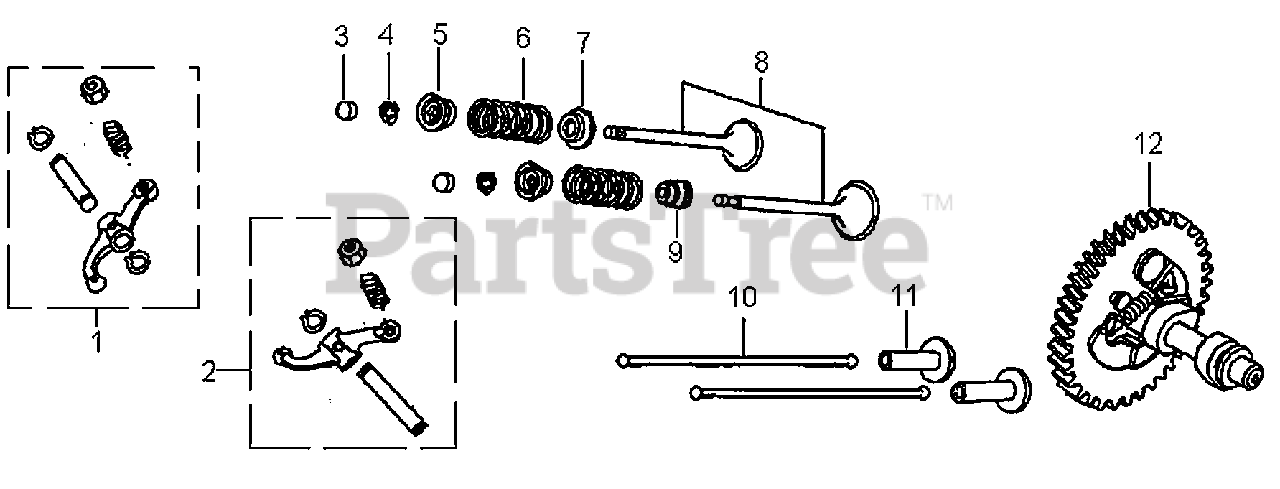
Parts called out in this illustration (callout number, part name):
1	ROCKER ARM ASSY.
2	ROCKER ARM ASSY.
3	ROTATOR,VALVE
4	VALVE LOCKER
5	RETAINER,VALVE SPRING
6	SPRING,VALVE
7	SEAT,VALVE SPRING
8	VALVE ASSY.
9	SEAL,VALVE STEM
11	LIFTER , VALVE
12	CAMSHAFT ASSY
